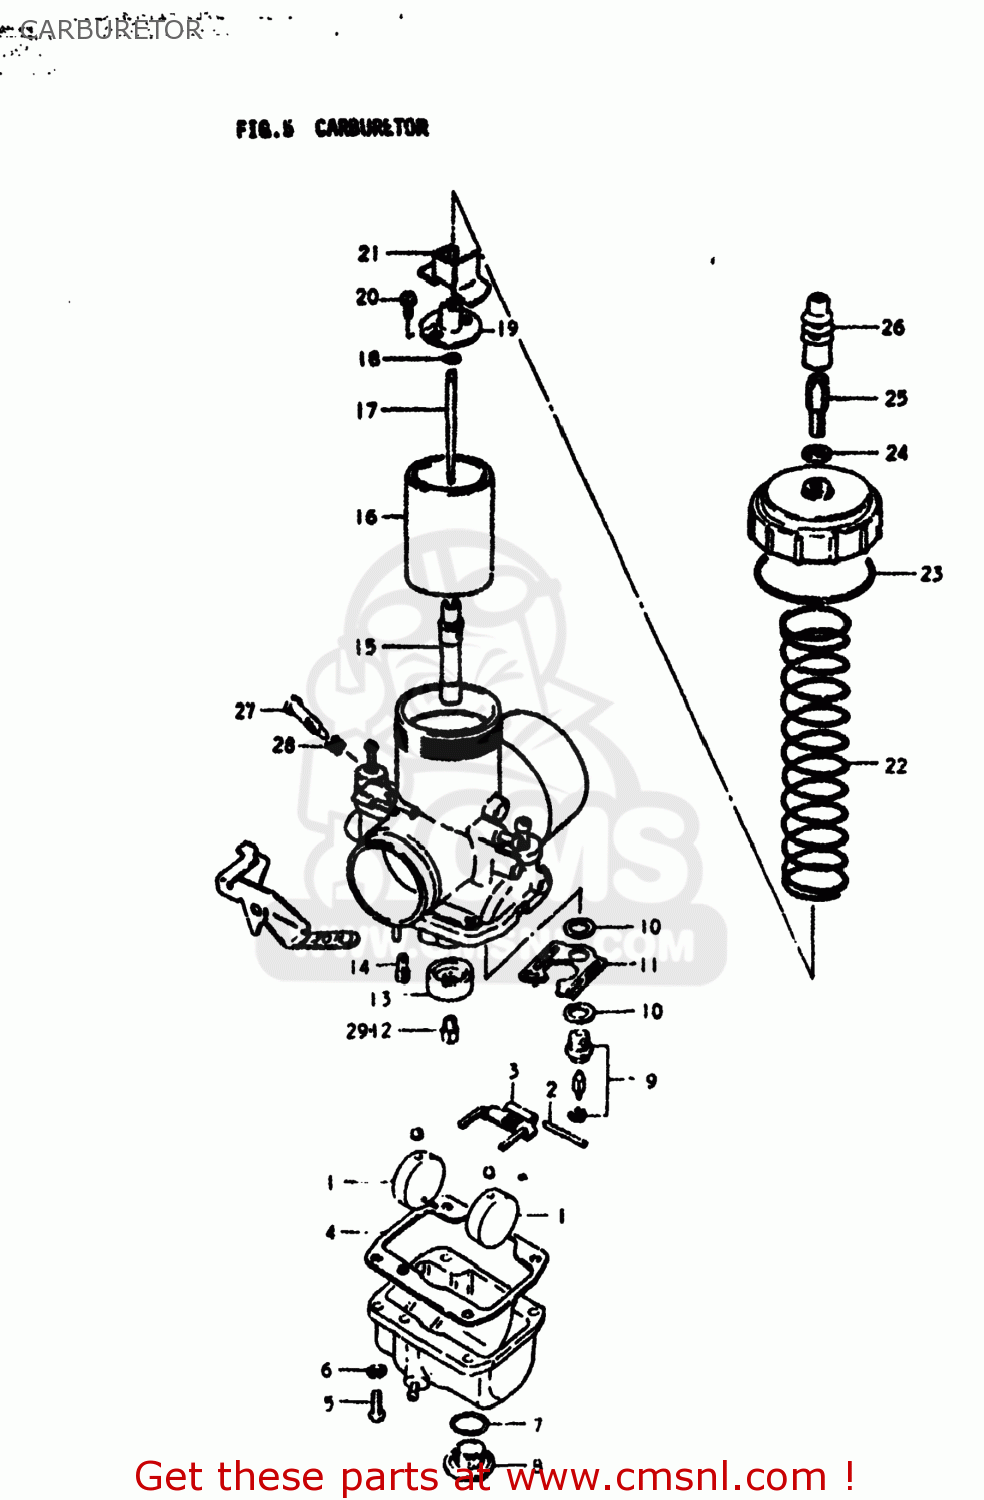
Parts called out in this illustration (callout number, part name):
1	FLOAT
2	PIN,FLOAT
3	ARM,FLOAT
4	GASKET,FLOAT CAHMBER (NAS)
5	SCREW
6	LOCK WASHER
7	O-RING
8	PLUG
9	VALVE ASSEMBLY,NEEDLE
10	GASKET,MAIN JET HOLDER (NAS)
11	PLATE
12	JET
13	RING
14	JET,PILOT
15	JET,NEEDLE
16	VALVE,THROTTLE
17	JET,NEEDLE(6FJ6-3)
18	CLIP
19	CONNECTOR
20	SCREW
21	COVER,HOLDER
22	SPRING,THROTTLE VALVE RETURN
23	GASKET,MIXING CHAMBER (NAS)
24	NUT
25	ADJUSTER,CABLE
26	CAP,CABLE ADJUSTER
27	SCREW,PILOT AIR
28	SPRING
29	JET
